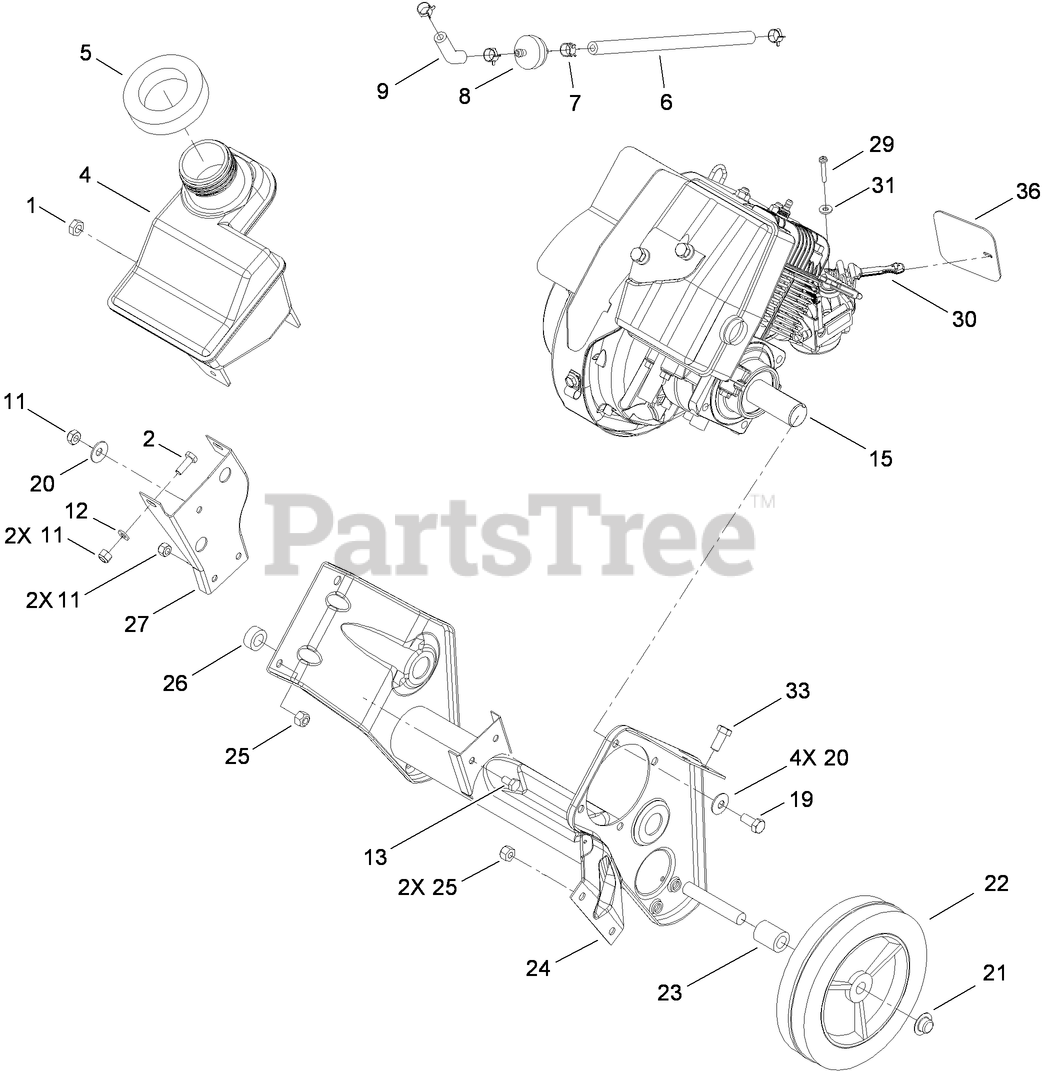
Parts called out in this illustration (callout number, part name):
1	NUT-LOCK, CONE
2	SCREW-HH
4	TANK-GAS
5	SEAL-FOAM
6	HOSE-FUEL
7	CLAMP-HOSE
8	FILTER-FUEL
9	HOSE-FUEL
11	NUT-LOCK, NI
12	WASHER-FLAT
13	SCREW-HH
19	SCREW-HH
20	WASHER-BELLEVILLE
21	NUT-PUSH
22	WHEEL
23	SPACER-WHEEL
25	NUT-LOCK, NI
26	SPACER-WHEEL
27	BRACKET-SUPPORT, RECOIL
29	SCREW-PPH, PLASTITE
30	LEVER-CHOKE
31	WASHER-FLAT
33	SCREW-HH
36	SHIELD-CHOKE HOLE
